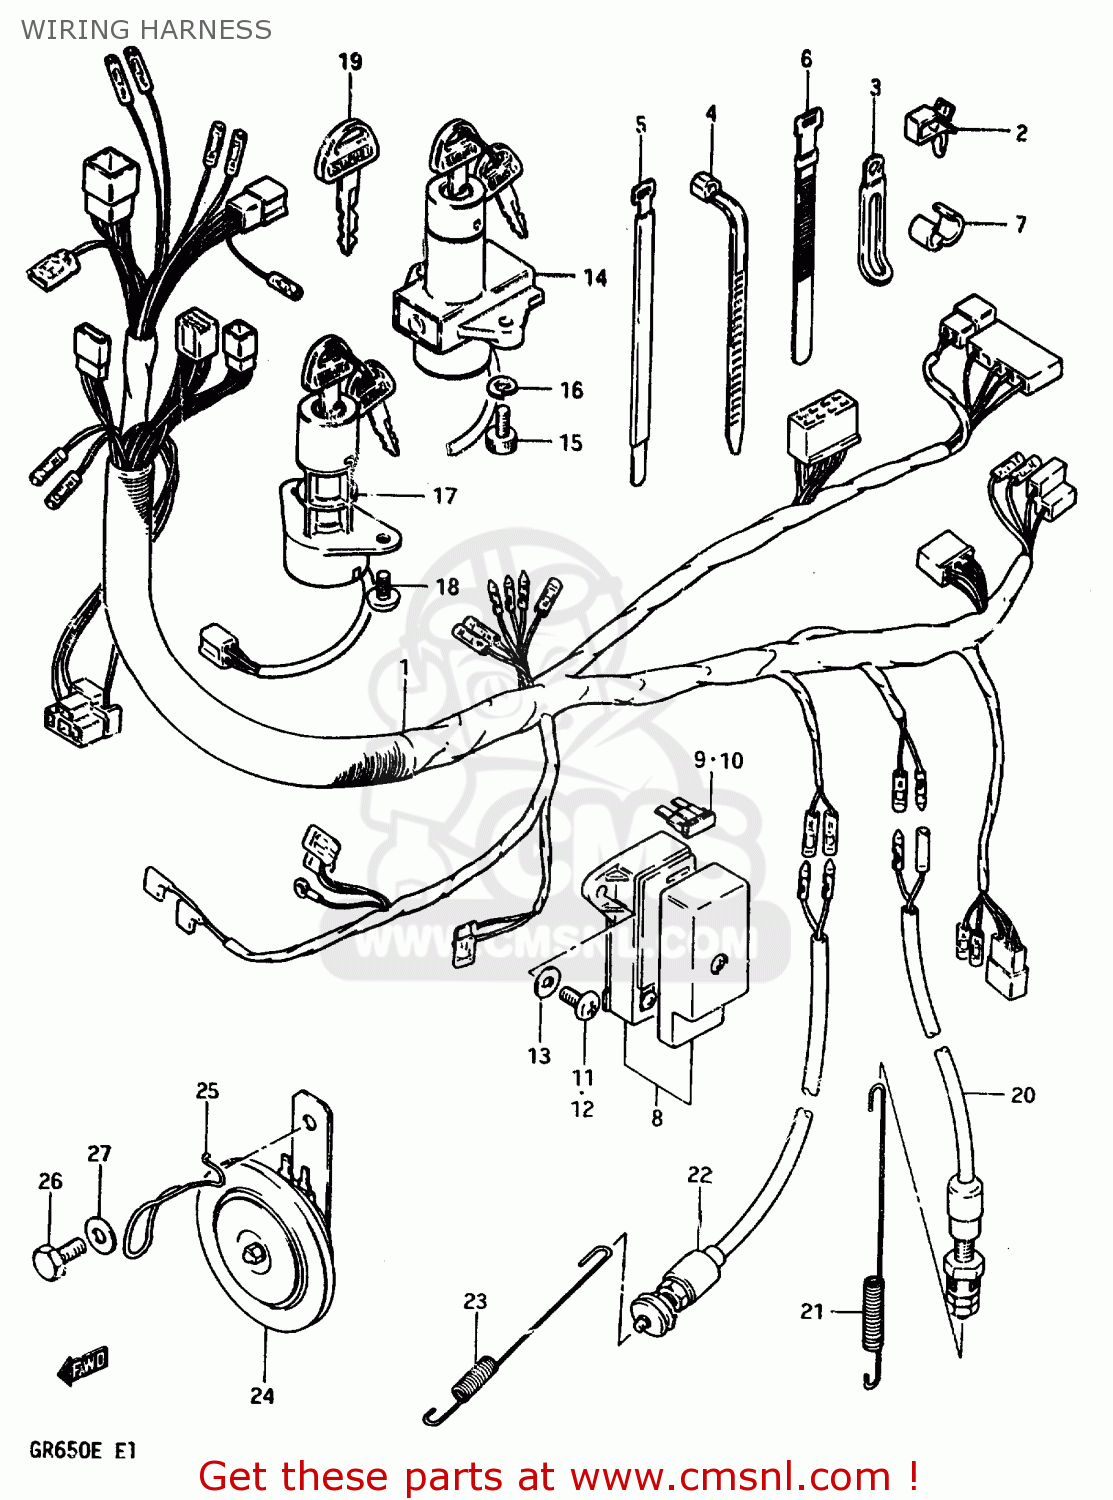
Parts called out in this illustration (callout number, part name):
1	HARNESS,WIRING
2	CLIP
3	CLAMP
4	CLAMP(L:125)
5	CLAMP
6	CLAMP(L:120)
7	CLIP
8	BOX ASSEMBLY,FUSE
9	FUSE(10A)
10	FUSE(15A)
11	SCREW
12	SCREW
13	WASHER, LOWER
14	SWITCH ASSY,IGNITION
15	BOLT
16	LOCK WASHER
17	SWITCH ASSEMBLY,IGNITION
18	SCREW 6X12
19	KEY,BLANK
20	SWITCH ASSEMBLY,STOP LAMP
21	SPRING
22	SWITCH ASSEMBLY,SIDE STAND
23	SPRING
24	HORN ASSY
25	PROTECTOR, HORN
26	BOLT
27	WASHER,8.5X16X
